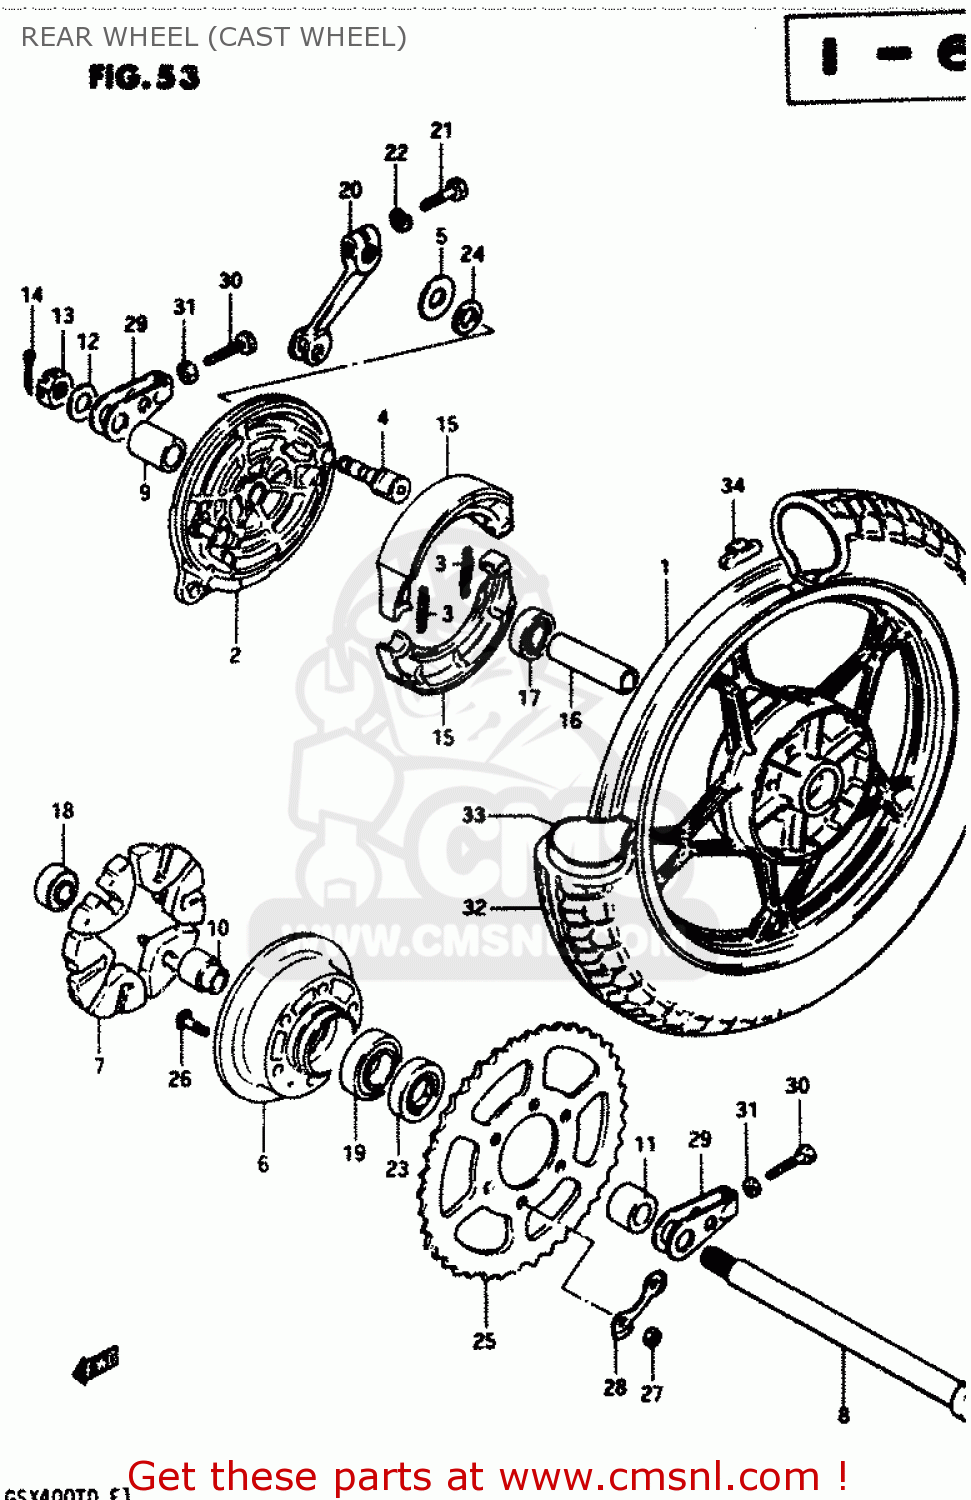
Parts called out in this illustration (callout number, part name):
1	WHEEL,REAR
2	PANEL,REAR HUB
3	SPRING,BRAKE SHOE
4	CAM,FRONT BRAKE
5	WASHER (15X24X1.6)
6	DRUM,REAR SPROCKET MOUNT
7	ABSORBER,RR HUB SHOCK
8	AXLE,REAR
9	SPACER(17.5X28X44.8)
10	SPACER,REAR HUB BEARING
11	SPACER(17X30.5X22.3)
12	WASHER (17X30X3.2)
13	NUT
14	PIN,COTTER
15	SHOE,BRAKE
16	SPACER (17.6X24X57)
17	BEARING
18	BEARING
19	BEARING
20	LEVER,RR BRAKE CAM
21	BOLT
22	LOCK WASHER
23	SEAL,OIL(30.5X52X8)
24	O-RING,BOSS
25	SPROCKET,REAR (NT:43)
26	BOLT
27	NUT
28	WASHER
29	ADJUSTER,CHAIN
30	BOLT 8X50
31	NUT
32	TIRE
33	TUBE ASSEMBLY,WHEEL,INNER
34	BALANCER,WHEEL
